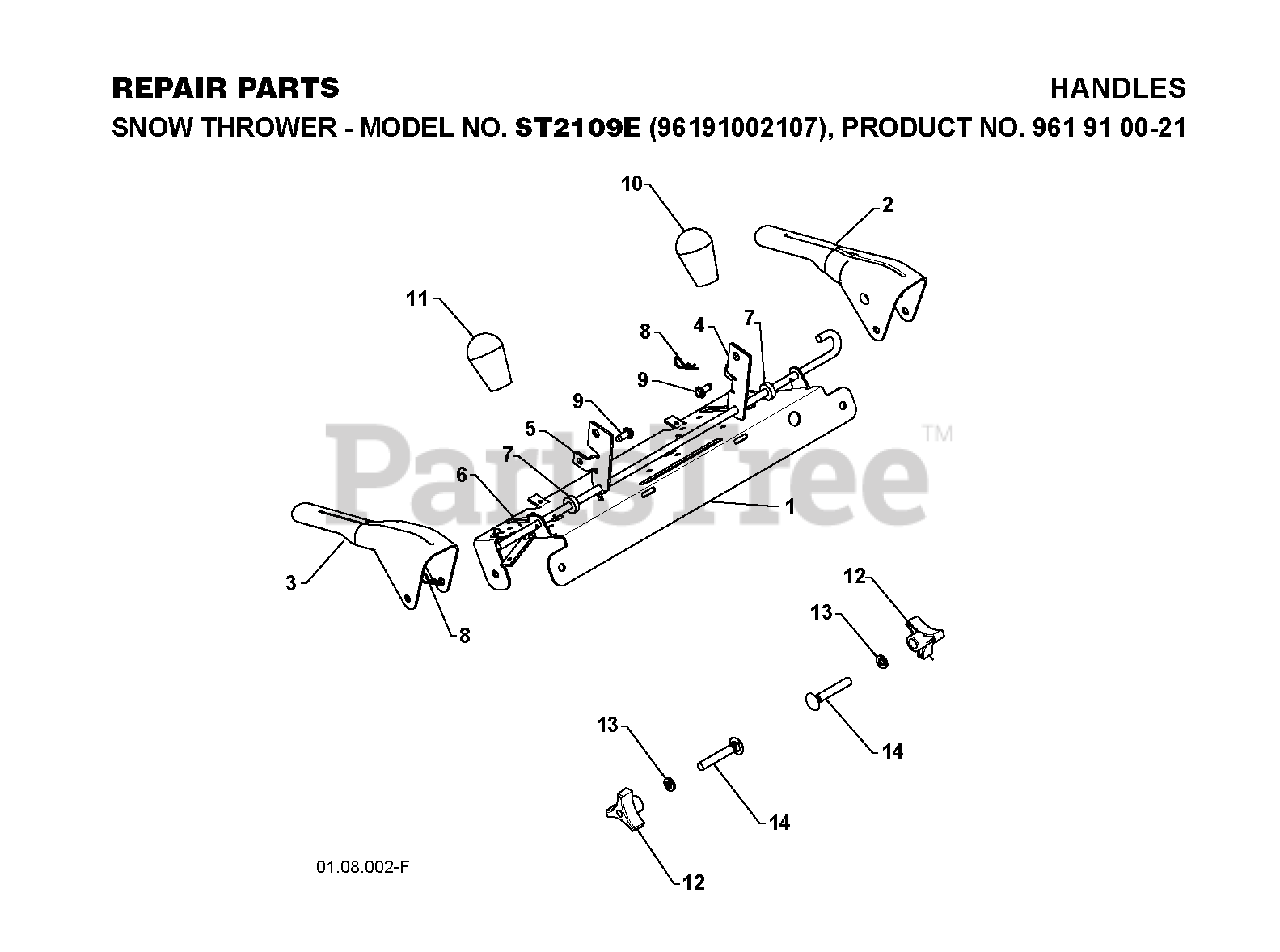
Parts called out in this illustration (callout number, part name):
1	PANEL.CONTROL.PNT.BLACK
2	LEVER.CONTROL.LH.BLACK
3	CONTROLLEVERRH
4	ARM.TRACTION.ROD.YZ
5	ARM.IMPELLER.ROD.
6	BAIL.CONTROL.INTERLOCK
7	SPACER.CONTROL.LEVER
8	SPRING RETAINER
9	SCREW 14-20 X 5/8
10	KNOB LEVER, BLACK
11	RED KNOB SHIFTER
12	KNOB.HANDLE.3/8.TRI-POINT.BLAC
14	BOLT 3/8-16 X 2-1/4
